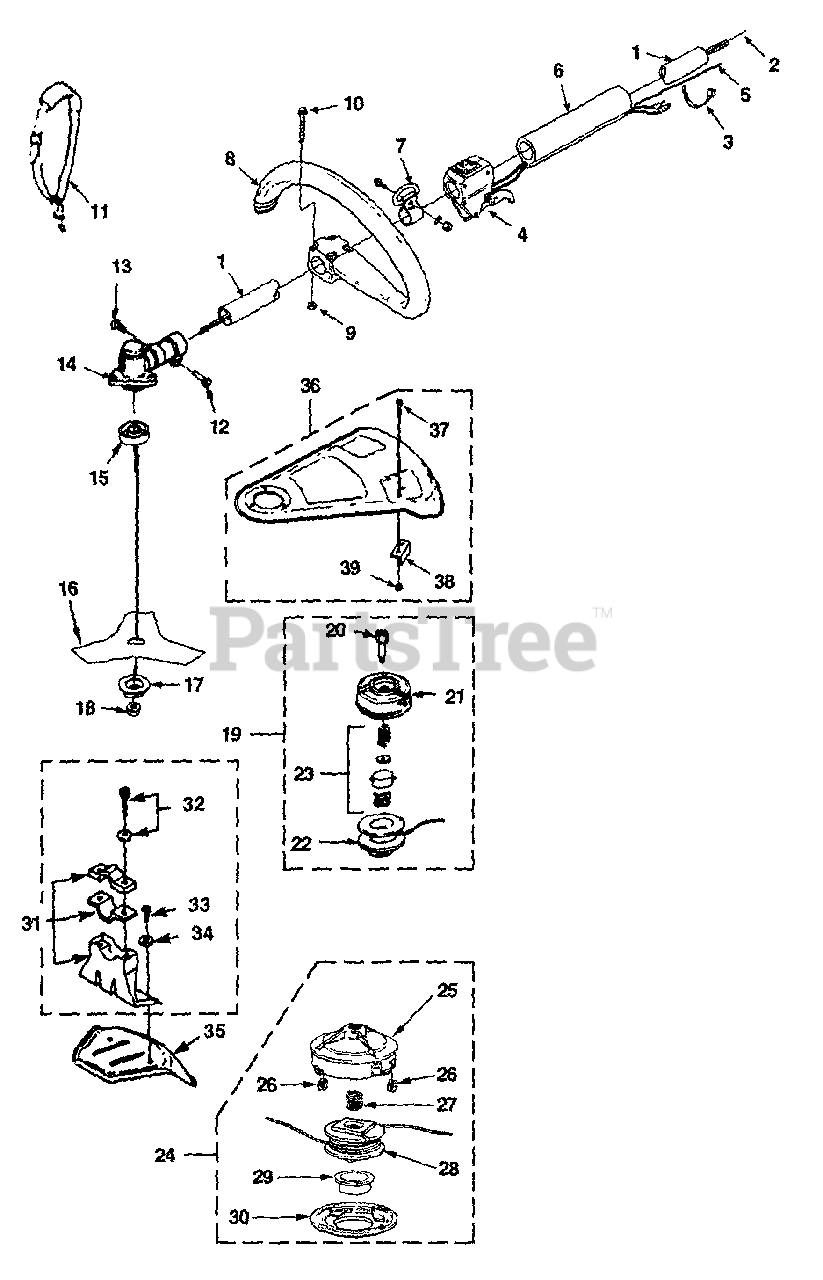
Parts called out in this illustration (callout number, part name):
1	HOUSING-Driveshaft
1	HOUSING-with Driveshaft
2	DRIVESHAFT
3	TIE-Cable
4	THROTTLE & SWITCH
5	THROTTLE CABLE
6	HIP PAD
8	HANDLE-Front
9	NUT (10-24)
10	SCREW
11	STRAP
12	SCREW-Cap Socket Hd (1/4-20 X 7/8")
13	SCREW-Sems Hex Hd (10-24 X 1/2")
14	GEAR HEAD
15	WASHER-Flanged
16	BLADE-Tri-Arc
17	WASHER-Flange (Lower)
18	NUT-Lock
19	STRING HEAD
20	BOLT, Shaft
21	HOUSING w/Eyelets
22	SPOOL & STRING
23	REPAIR KIT
24	STRING HEAD
25	HOUSING, String
28	SPOOL W/String
29	BUTTON
31	DEFLECTOR BRACKET KIT
32	SCREW & WASHER
33	SCREW-Machine (6M)
34	WASHER-Flat
35	BLADE GUARD
36	DEFLECTOR-Grass
37	SCREW-Mach Hex Hd. (10-24 x 3/8")
38	BLADE-Cut-Off
39	NUT-(10-24)
